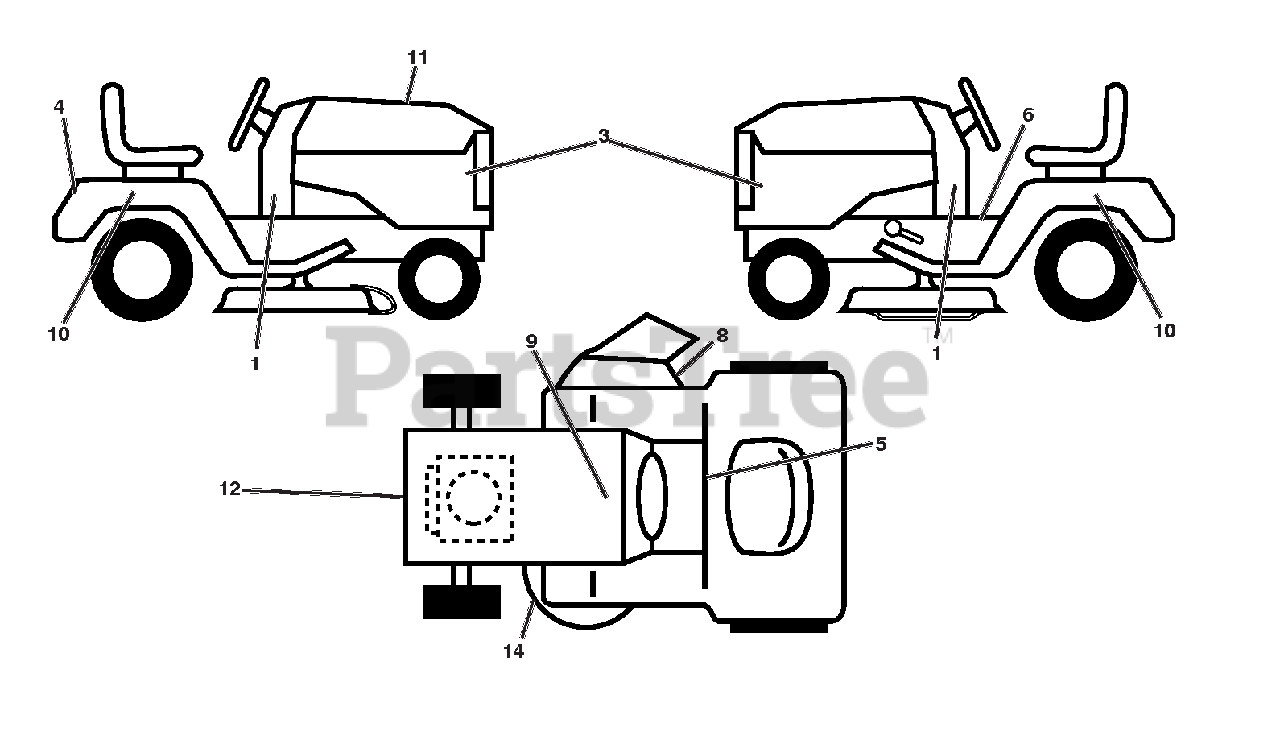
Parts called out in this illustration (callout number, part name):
1	DECAL.DASH
3	DECAL.SDPNL.PWRDBY B&S.ARIENS
4	DECAL.FENDER.REAR.ARIENS
5	DECAL.FENDER
6	DECAL.WARNING.START
8	DECAL.WARNING.KEEP.HAND.AWY
9	DECAL.BAT.DAN/POI P/L SYM.WPN
10	DECAL.FENDER.SIDE.HYDRO
11	DECAL REPLACEMENT
12	DECAL.ENGINE
14	DECAL.V-BELT.SCH.
